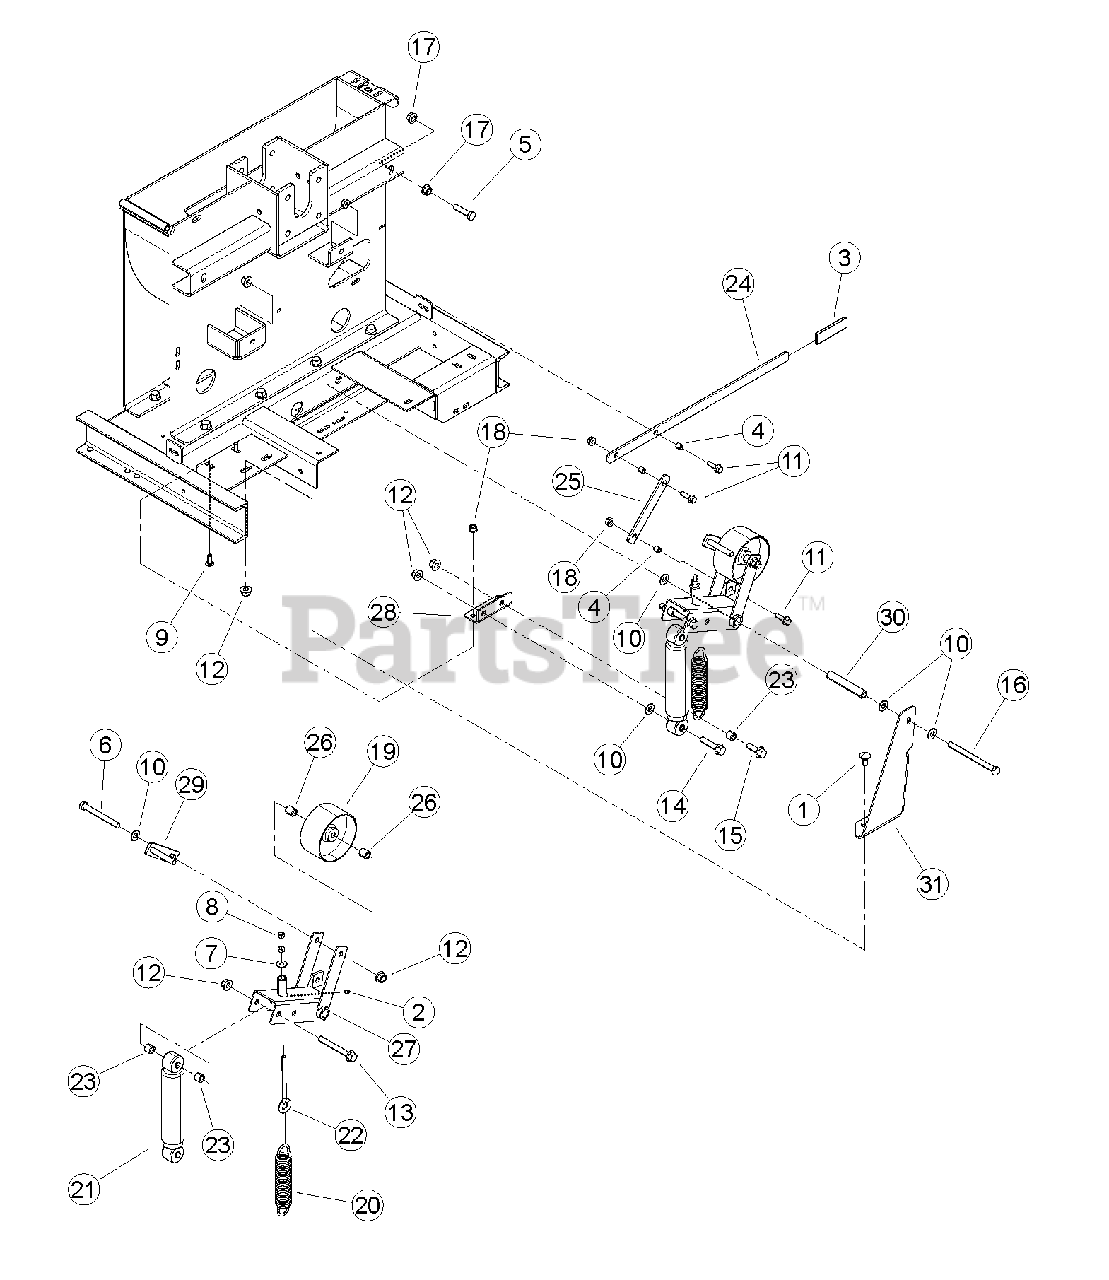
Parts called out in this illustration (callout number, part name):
1	BOLT, 1/2 X 1 GR5 CRG ZP
2	FITTING, 1/4 SELF-TAP GREASE
3	GRIP, CLUTCH HANDLE
4	BUSHING, 3/8 X 1/2 SLEEVE LUBE
5	BOLT, 1/2 X 2 GR5 HEX CAPSCREW ZP
6	BOLT, 1/2 X 4-1/2" GR5 HHCS NC ZP
7	WASHER, 3/8" FLAT ZP
8	NUT, 3/8" HEX NC ZP
9	BOLT, 3/8 X 1" GR5 CRG NC ZP
10	WASHER, 1/2" SAE FLAT ZP
11	BOLT, 3/8 X 1-1/4 FLANGE NC
12	NUT, 1/2-13 NYLOCK FLANGE
13	BOLT, 1/2-13 X 4 HWH GR5 CZP
14	BOLT, 1/2 -13 X 2-1/4 FLANGE NC
15	BOLT, 1/2-13 X 1-1/2 GR5 FLANGE NC
16	BOLT, 1/2 X 6 G5 HCS - ZP
17	NUT, 1/2 SPIRAL LOCK NC ZP
18	NUT, 3/8-16 NYLOCK FLANGE
19	PULLEY, IDLER 5" X 2.50"
20	SPRING, 7-3/4" EXTENSION
21	ABSORBER, IDLER SHOCK
22	EYEBOLT, 3/8 X 5" LG 4-1/4 THD ZP
23	SPACER, 0.75 X 0.620
24	LEVER, CLUTCH ENGAGEMENT
25	LINK, ENGAGEMENT ARM
26	SPACER, IDLER SHEAVE
27	WELDMENT, IDLER ARM
28	BRACKET, SPRING ANCHOR
29	WELDMENT, BELT PIN
30	BUSHING, IDLER PIVOT
31	BRACE, IDLER
